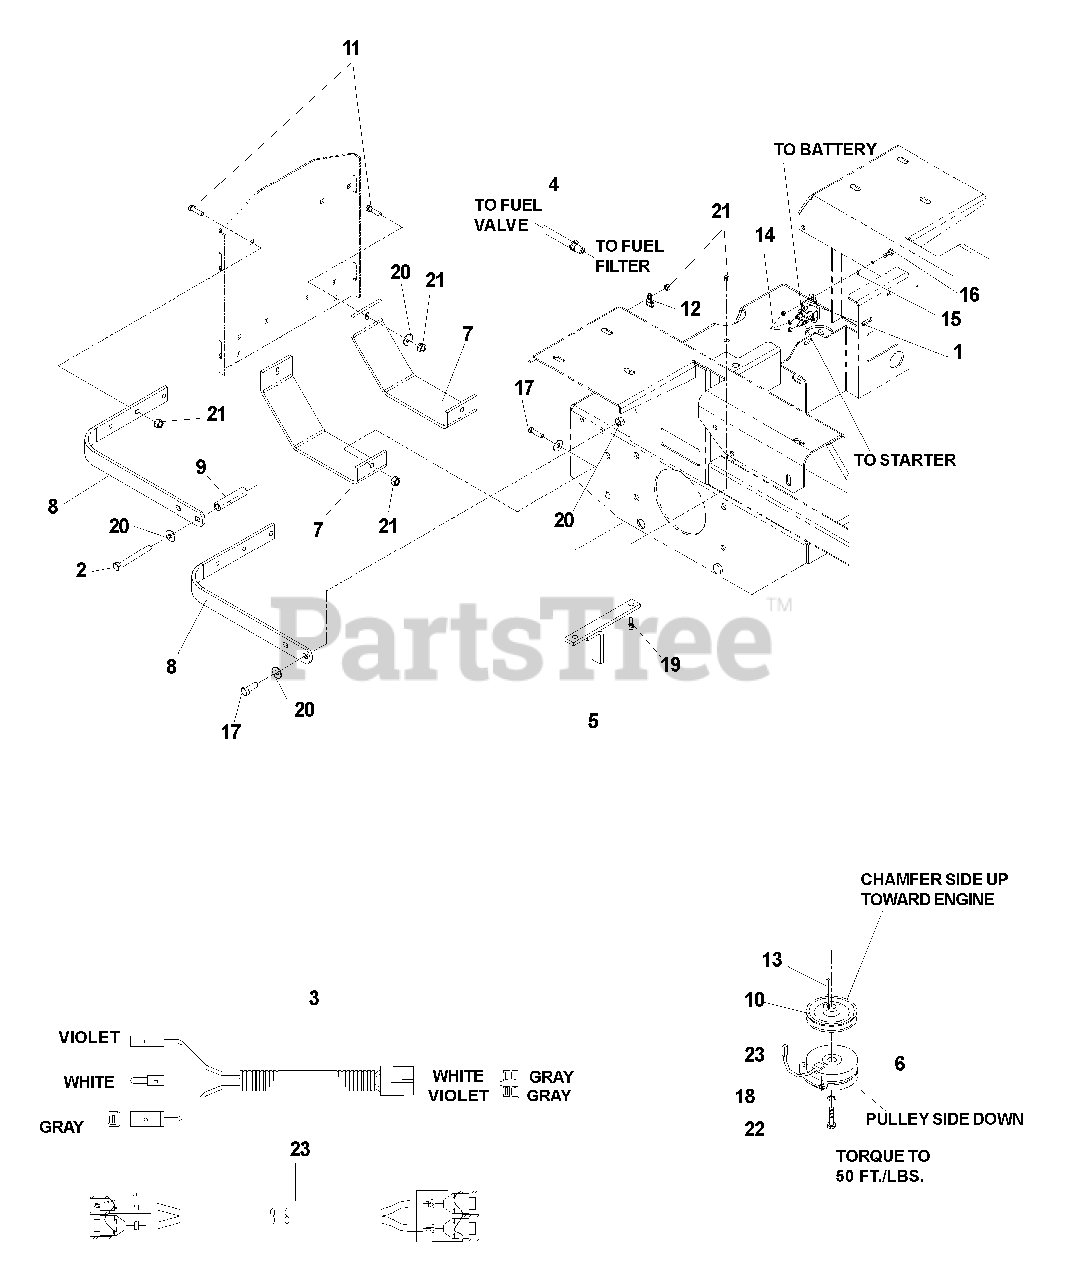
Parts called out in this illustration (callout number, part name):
2	HCS, 5/16-18 X 4, GR5
3	PIGTAIL, KAWASAKI
4	FUEL LINE HOSE
5	CLUTCH TIE DOWN
7	SKID PLATE
11	RHSNB, 5/16-18 X 1, GR5
12	CLAMP, DOUBLE TUBE
13	KEY, 1/4 SQ X 1 1/4
14	NUT, 1/4-20, NYLOC
15	WASHER, 1/4
16	HCS, 1/4-20 X 5/8, GR5
17	HCS, 5/16-18 X 1, GR5
18	LOCKWASHER, 7/16
19	HCS, 5/16-18 X 1 3/4, GR5
20	WASHER, 5/16
21	NUT, 5/16-18, NYLOC
22	HCS, 7/16-20 X 2 1/2, GR5
23	CLUTCH HARNESS
